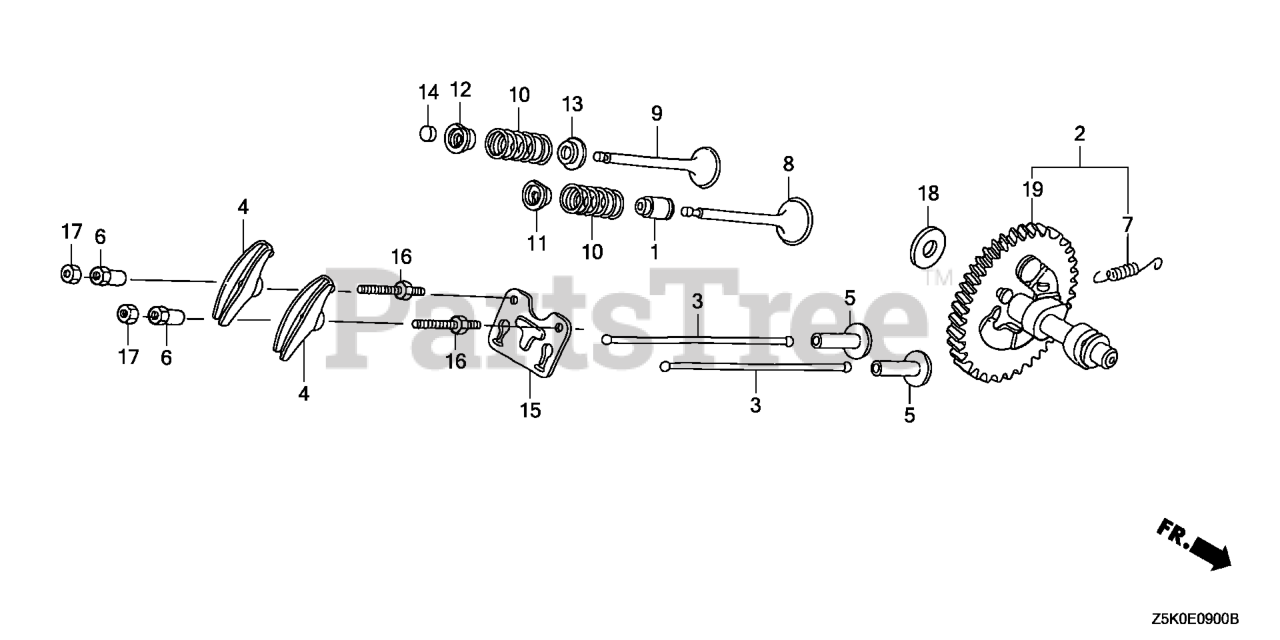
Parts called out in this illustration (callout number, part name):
1	SEAL, VALVE STEM
2	CAMSHAFT (STD) (PRESS FIT CAM)
2	CAMSHAFT COMP (STD)
4	ARM, VALVE ROCKER
5	LIFTER, VALVE
6	PIVOT, ROCKER ARM
7	SPRING, WEIGHT RETURN
8	VALVE, IN.
9	VALVE, EX.
10	SPRING, VALVE
11	RETAINER, IN. VALVE SPRING (EXHAUST SIDE)
12	RETAINER, IN. VALVE SPRING (EXHAUST SIDE)
13	SEAT, VALVE SPRING
15	GUIDE, PUSH ROD
16	BOLT, PIVOT (8MM)
17	NUT, PIVOT ADJ.
19	CAMSHAFT (STD) (PRESS FIT CAM)
19	CAMSHAFT COMP (STD)
